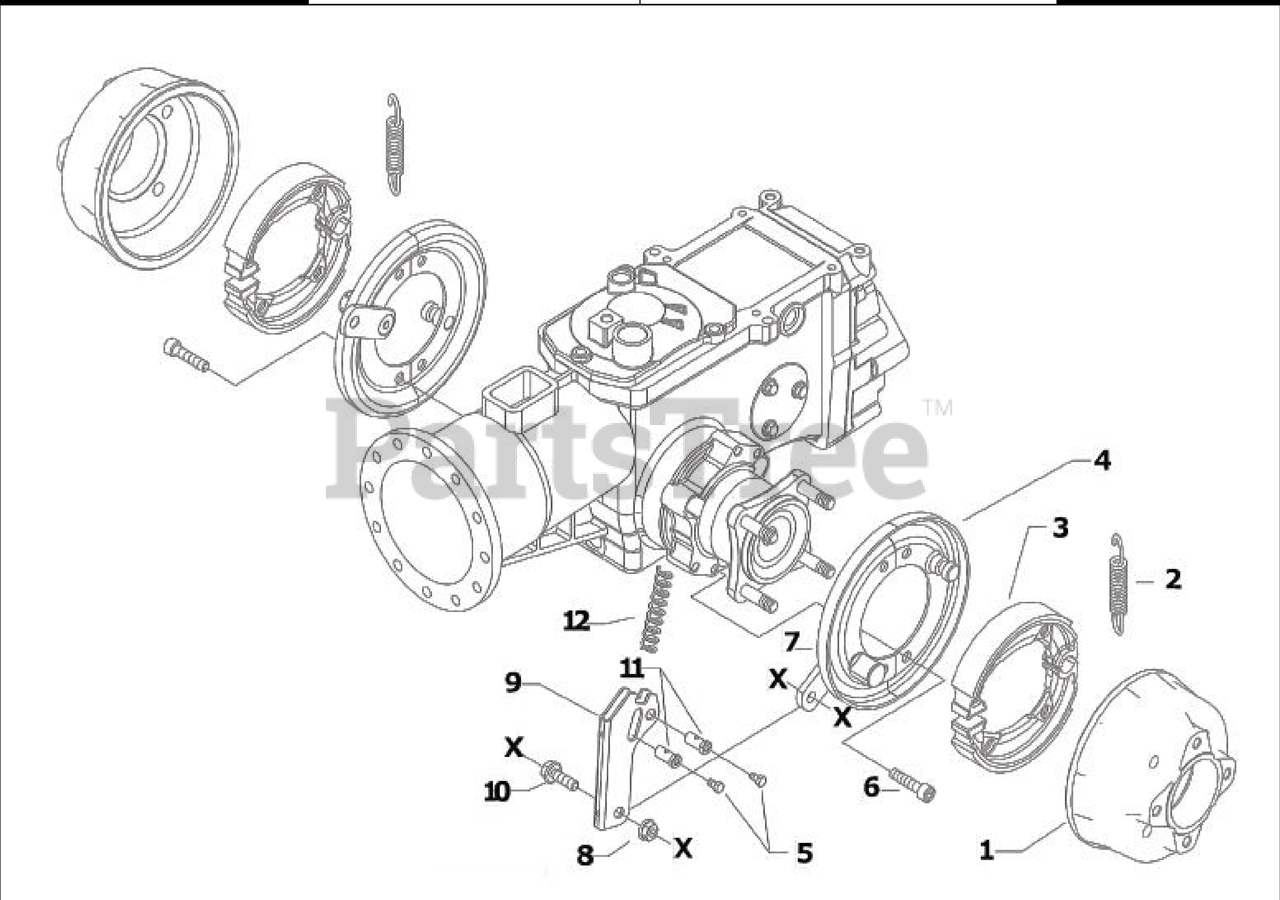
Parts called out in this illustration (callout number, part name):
1	BRAKE DRUM
5	SCREW TE M6X16 UNI 5739 8G
6	SCREW TCEI M8X25 UNI 5931
7	HALF DISC WITH LEVER
8	SELFLOCK NUT M8 6S
9	FORK
10	SCREW TE C/F M8X25 DIN 6921 8G
11	CLAMPING SCREW
